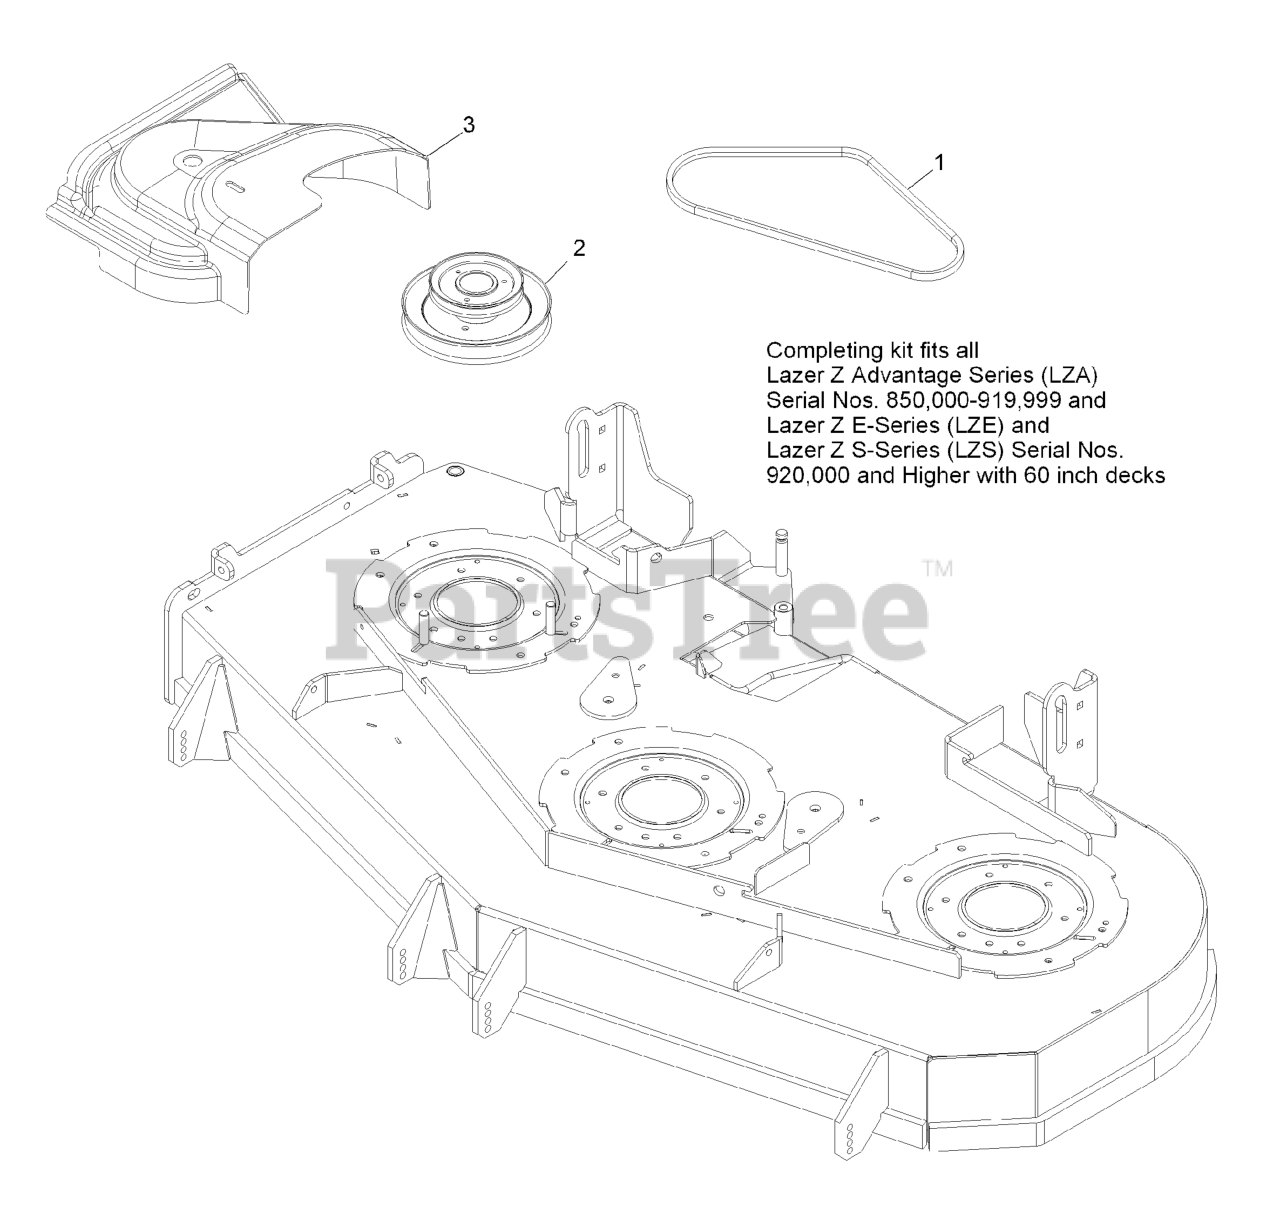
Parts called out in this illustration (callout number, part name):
1	BELT, BLOWER DRIVE 60
2	JACKSHAFT,UV DRIVE 604 SPLINED
3	COVER,BELT UV 60
